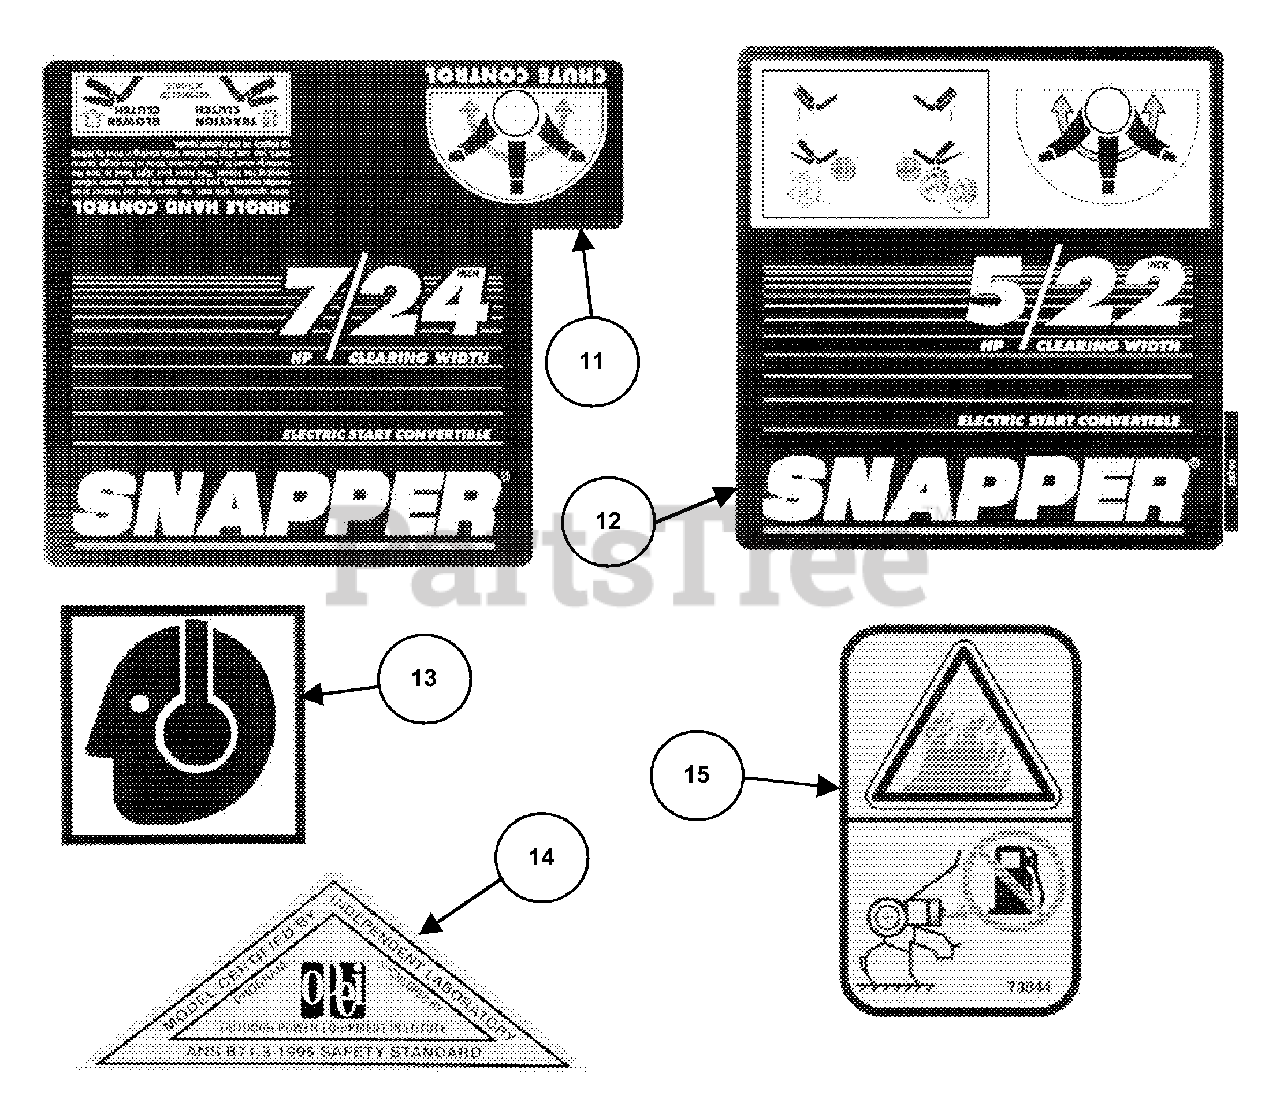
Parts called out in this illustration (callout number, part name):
11	DECAL, Control- 7/24
12	DECAL, Control- E5/22
13	DECAL, Ear Protection
14	DECAL, OPEI Snow
15	DECAL, Fuel Safety
